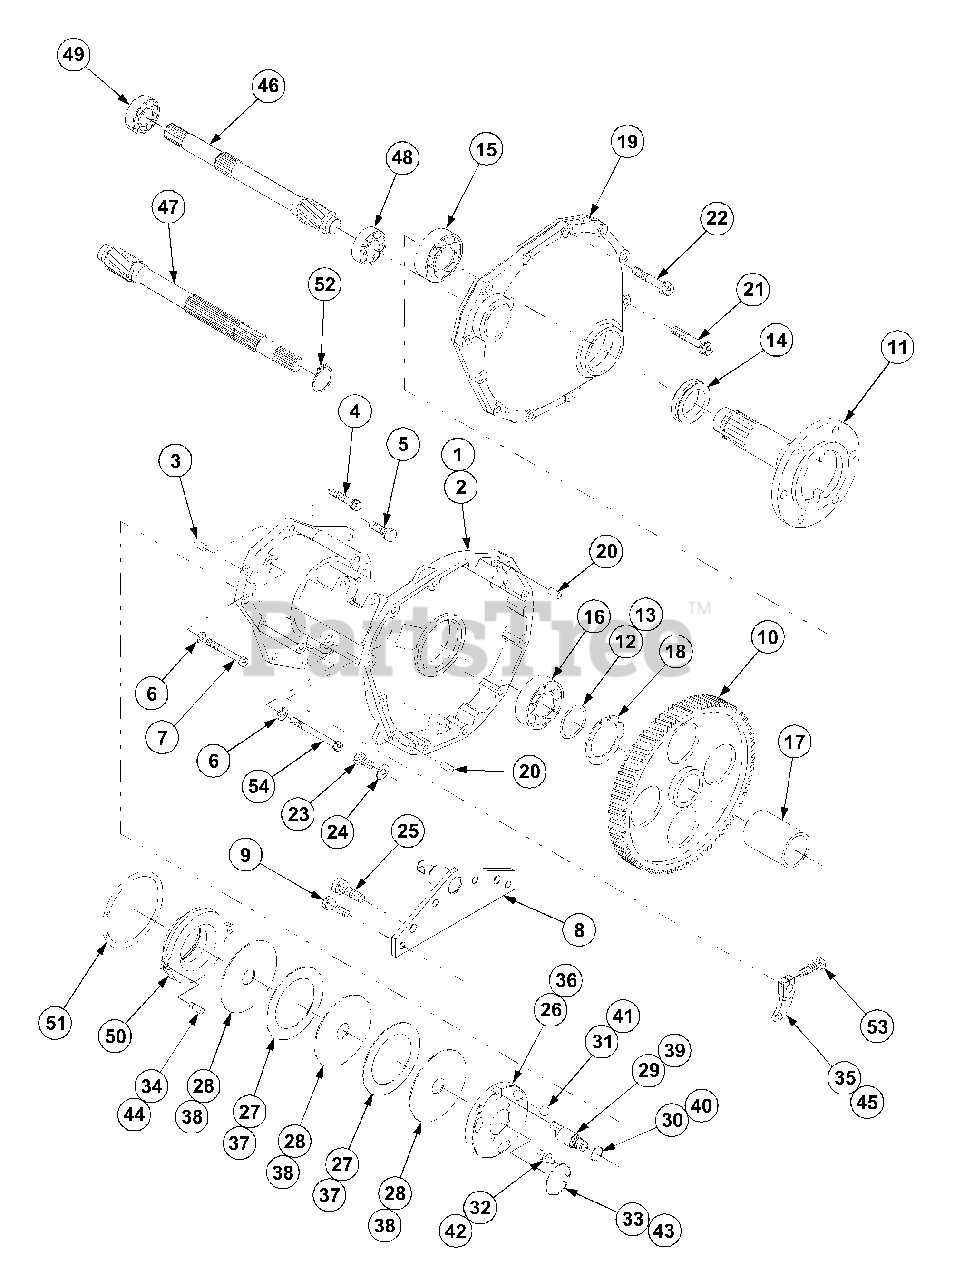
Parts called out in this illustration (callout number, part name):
1	Axle Case L.H
2	Axle Case R.H
4	Bolt,w/Washer
5	Bolt,w/Washer
6	Washer,Spring
8	Bracket
9	Bolt,w/Washer
18	C-Ring
21	Bolt,w/Washer
22	Bolt,w/Washer
25	Bolt,w/Washer
46	Shaft Diff L.H
47	Shaft Diff R.H
52	C-Ring
53	Bolt,w/Washer
